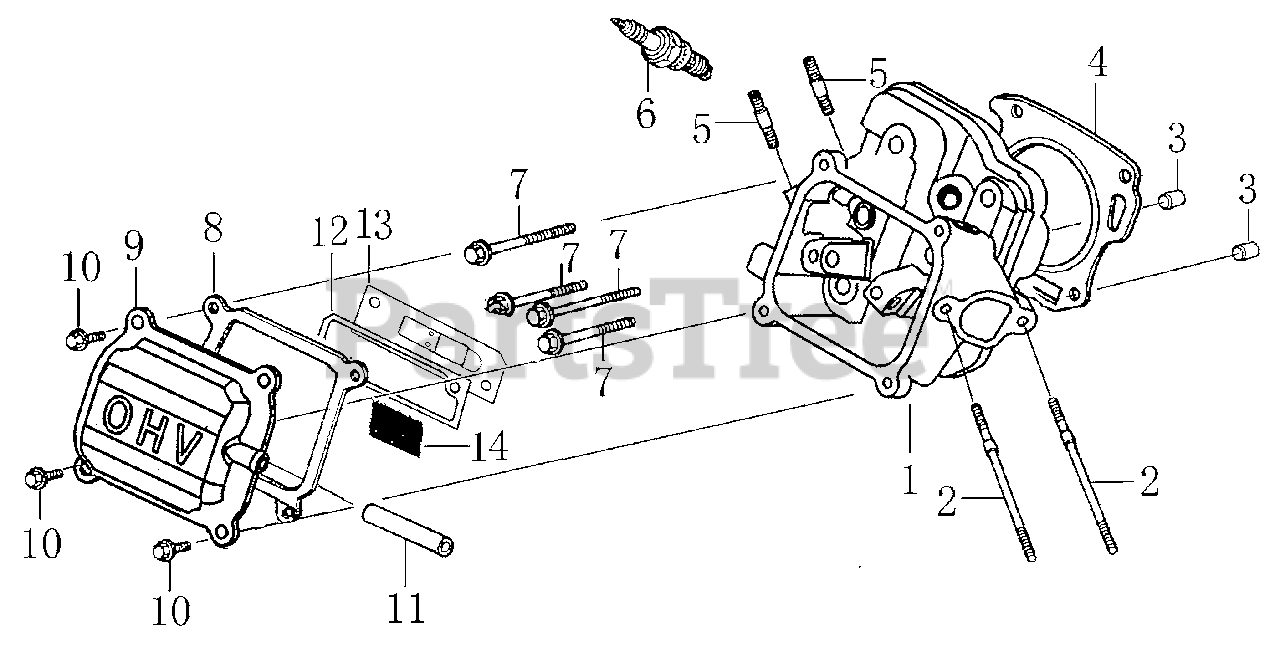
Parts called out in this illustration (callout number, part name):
1	HEAD, CYLINDER
2	BOLT, STUD, IN.
3	PIN, DOWEL
4	GASKET, CYLINDER
5	BOLT, STUD, EX.
6	PLUG, SPARK
7	BOLT, FLANGE , 8x60
8	GASKET, HEAD COVER
9	COVER, HEAD
10	BOLT, FLANGE , 6x14
11	TUBE, BREATHER
12	GASKET, BREATHER CHAMBER
13	CAP, BREATHER CHAMBER
14	OIL STRAINER
